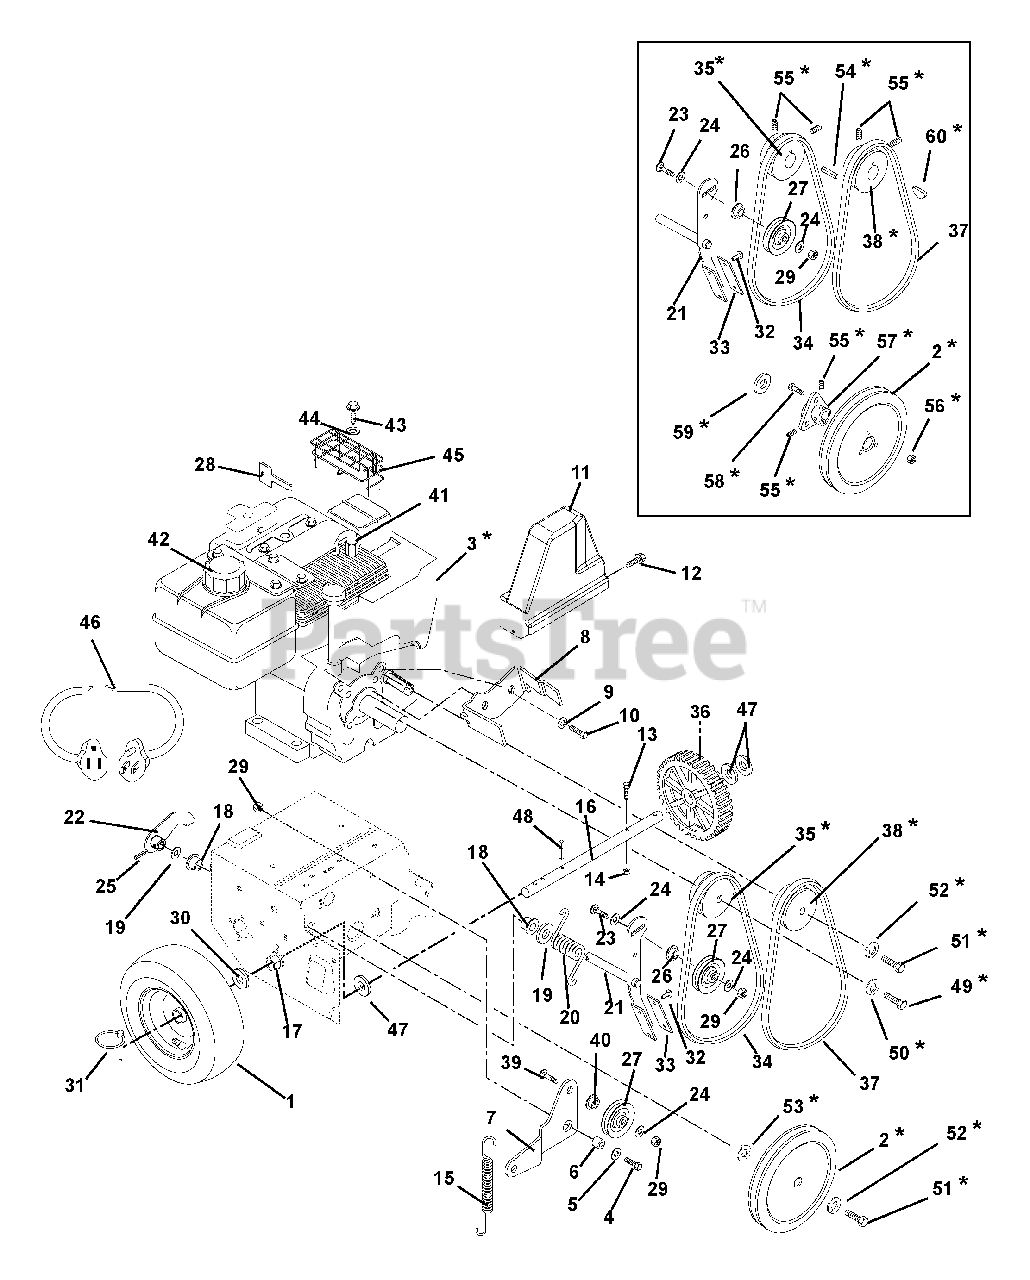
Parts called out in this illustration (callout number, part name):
1	WHEEL, 4.1-6
2	PULLEY, 3L W/HUB, .625 X 8.0
3	ENGINE, 5HP TEC LH195SA RECOIL
4	@BLT-HEX .31-18X.75 GR5 YWZC
5	@WSHR-FL-STL.38X.875X.083 YWZC
6	SPACER BUSHING .5 X .32 X .163
7	IDLER ARM
8	FINGER, BELT
9	WSHR-LK .312X.097 HVY YWZC
10	BLT-HEX .31-24X.75 YWZC GR5
11	COVER, BELT
12	@SCR-TAP .25-20X.37 HWH YWZ TR
13	BLT-HEX .25-20X1.75 GR8 YWZC
14	@NUT-LK-CTR .25-20 YWZC
15	SG-TENS .047X.44X3.37 WLD 1.47
16	AXLE SHAFT, COMPACT W/PIN LOCK
17	BSHG-FLG .750X.873HEXX.53X1.18
18	BSHG-FLG .500X.625X.500X.750
19	WSHR-FL-STL .520X.810X.033YWZC
20	SG-TORS .148X1.0X1.53
21	CLUTCH ARM W/BRAKE PAD
22	ARM-CLUTCH
23	@BLT-RDHDSQNK .31-18X1.25 G5YZ
24	@WSHR-FL-STL.38X.875X.083 YWZC
25	PIN-ROLL .156X.88
26	SPCR, BRG .315X.50X.688X.281
27	IDLER
28	KEY, PUSH/PULL - TECUMSEH
29	@NUT-LK-CTR .31-18 YWZC
30	WSHR-FL-STL.754X1.125X.062YWZC
31	PIN-LOK .31X1.75
32	RVT-TBLR .187X.437 RH ST PL
33	BRAKE LINING
34	BELT,4L TO BE REPLACED07200021
35	SHEAVE, ENGINE
37	V-BELT, 3L-COGGED
38	SHEAVE, CAMSHAFT OH/LH195SA
39	BLT-RDHDSQNK .31-18X1.0 SHTYZ
40	BSHG, FLG .325X.499X.26X.88
41	PLUG, SPARK
42	CAP, FUEL - TECUMSEH
43	SCR-TAP 10-16X.75 YWZC
44	@WSHR-FL-STL.219X.50X.049 YWZC
45	MUFFLER GUARD 5 HP
46	CORD, ELECTRIC START CORD 120V
47	WSHR-FL-STL .755X1.25X.125 YZ
48	PIN-ROLL .188X1.25
49	BLT-HEX .38-24X1.0 GR5 YZ EP80
50	@WSHR-LK .38X.094 REG YWZC
51	BLT-HEX .25-28X.75 GR5 YZ EP80
52	WSHR-LK .250X.077 HVY YWZC
53	WSHR-WAVE .69X.84X.011
54	KEY-SQ .188X1.0X.188 SAE 8630
55	SCR-SET .31-18X.38 SKHCUPDL
56	@NUT-SPNLK-FLG .312-18 YWZC
57	HUB
58	BLT-SERRDHD SL .31-18X.75 YZ
59	WSHR, THRUST .625X1.125X.063
60	KEY-WDRF .125X.625X.250 SAE5
